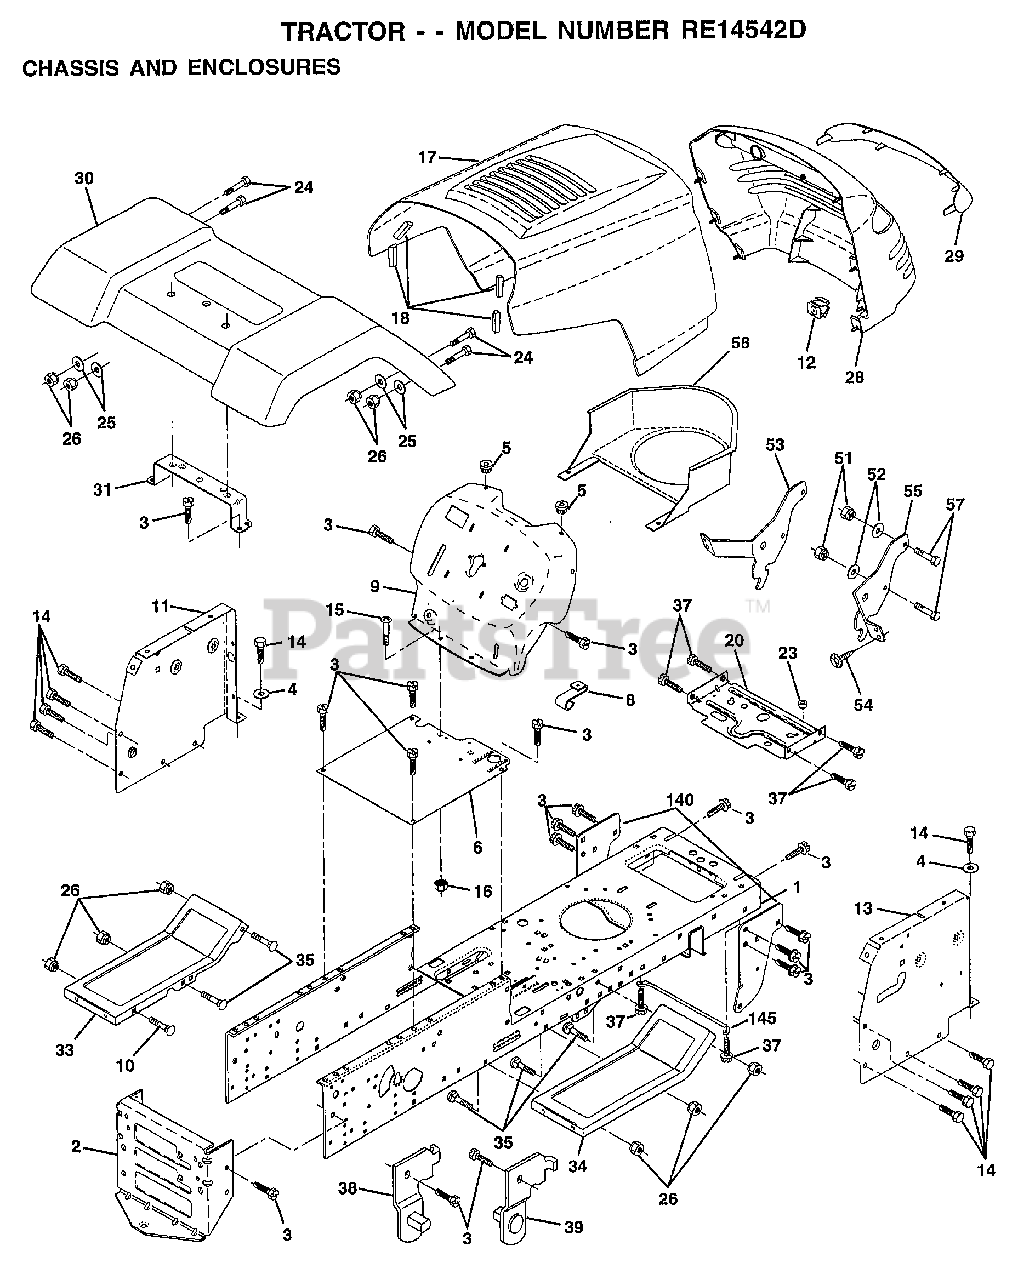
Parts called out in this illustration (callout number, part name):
1	CHASSIS.STAMPING
3	SCREW
4	WASHER
5	BUMPER-HOOD/DASH
6	SADDLE
8	CLIP.RETAINER
9	DASH SILKSCREEN
11	"PANEL-DASH,LH"
12	CLIP.TINNERMAN
13	PANEL.ASM.SLKSCR.DASH.RH
14	SCREW LT
15	SCREW
17	HOOD.STEEL.ASSY
20	"PLATE-MTG,BATT/FU"
24	BOLT
25	WASHER
26	NUT
28	GRILLE-MS428
29	LENS.GRILLE.PRIVATE LABEL
31	BRKT FENDER
33	FOOTREST LH
34	FOOTREST RH
35	BOLT
37	SCREW LT
38	BRACKET ASM LH
39	BRACKET ASM RH
51	NUT
52	WASHER
53	BRACKET.GRILLE.LH
54	SCREW.HEX.WS.HD
55	BRACKET.GRILLE.RH
58	DUCT.AIR.B&S.18HP
140	BRKT SUSPENSION
145	"ROD POVOT,CHASSIS"
